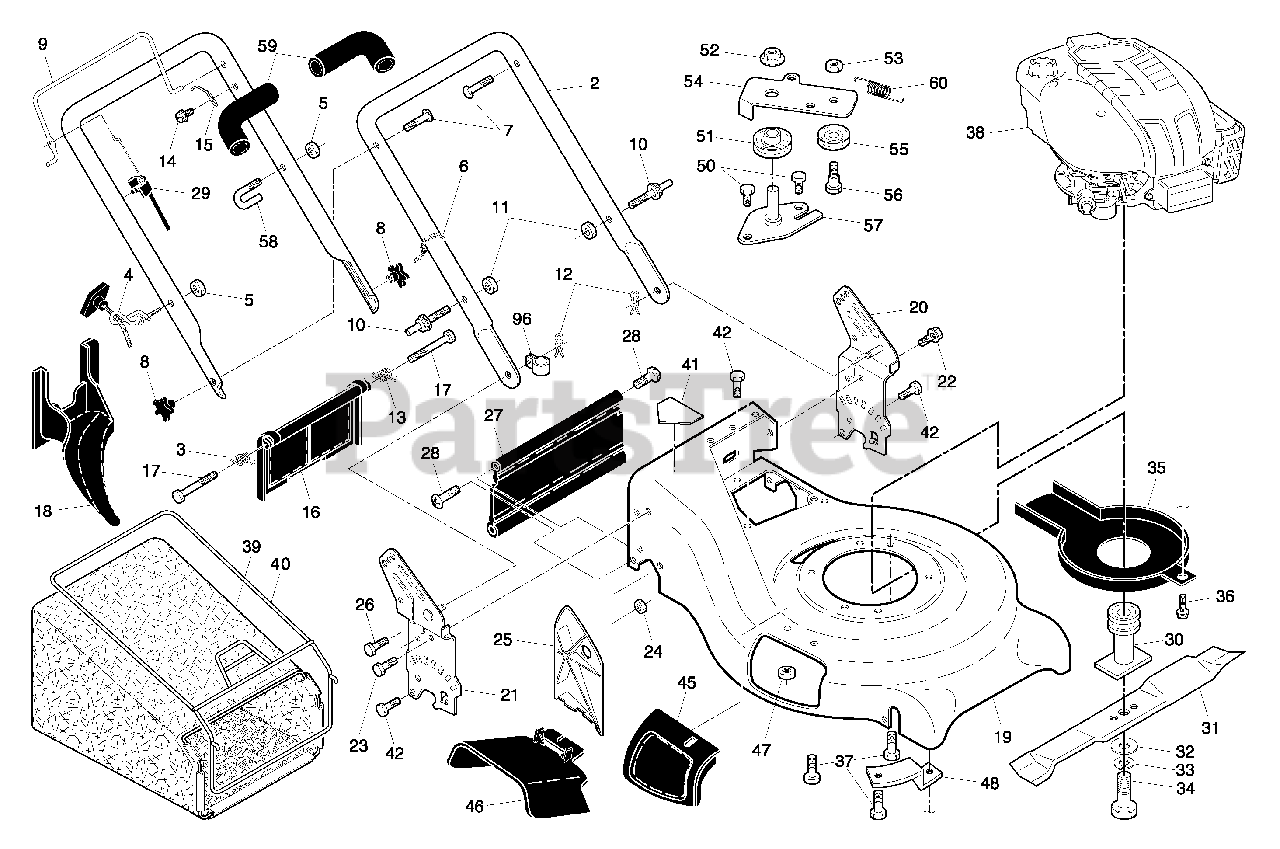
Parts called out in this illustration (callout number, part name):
1	Upper Handle Assembly
2	Handle, Lower
3	Spring, Rear Door, RH
4	Rope Guide
5	Nut, Hex, with Lockwasher Insert 1/4-20
6	Wire, Tie
7	Bolt, Handle 5/16-18 x 2-5/8
8	Knob, Handle
9	Control Bar
10	Pin, Handle Adjustment
11	Nut, Hex
12	Cotter, Hairpin
13	Spring, Rear Door, LH
14	Screw
15	Bracket, Upstop
16	Rear Door Assembly
17	Bolt, Rear Door
18	Plug, Mulcher
19	Kit, Housing
20	Handle Bracket Assembly, LH
21	Handle Bracket Assembly, RH
22	Screw, Hex Washer Head
23	Bolt, Hex Head 5/16-18 x 5/8
24	Nut, Hex, with Lockwasher Insert 5/16-18
25	Baffle, Side
26	Screw #12 x 5/8
27	Skirt, Rear
28	Screw, Hinge 1/4-20 x 1.25
29	Cable, Operator Presence
30	Blade Adapter / Pulley
31	Blade, 21"
32	Washer
33	Washer, Lock
34	Bolt, Hex Head
35	Debris Shield
36	Bolt
37	Bolt, Engine
39	Grassbag
40	Frame, Grassbag
41	Danger Decal
42	Screw
45	Mulcher Door Assembly
46	Discharge Guard
47	Nut, Hex
48	Mounting Bracket,Debris Shield
50	Screw
51	Pulley, Idler
52	Flanged Nut
54	Idler Arm
55	Idler Pulley
56	Shoulder Bolt
57	Bracket Assembly
58	Clip, Wireform (Packaging)
59	Grip, Foam
60	Spring, Return
96	Clip, Cable
